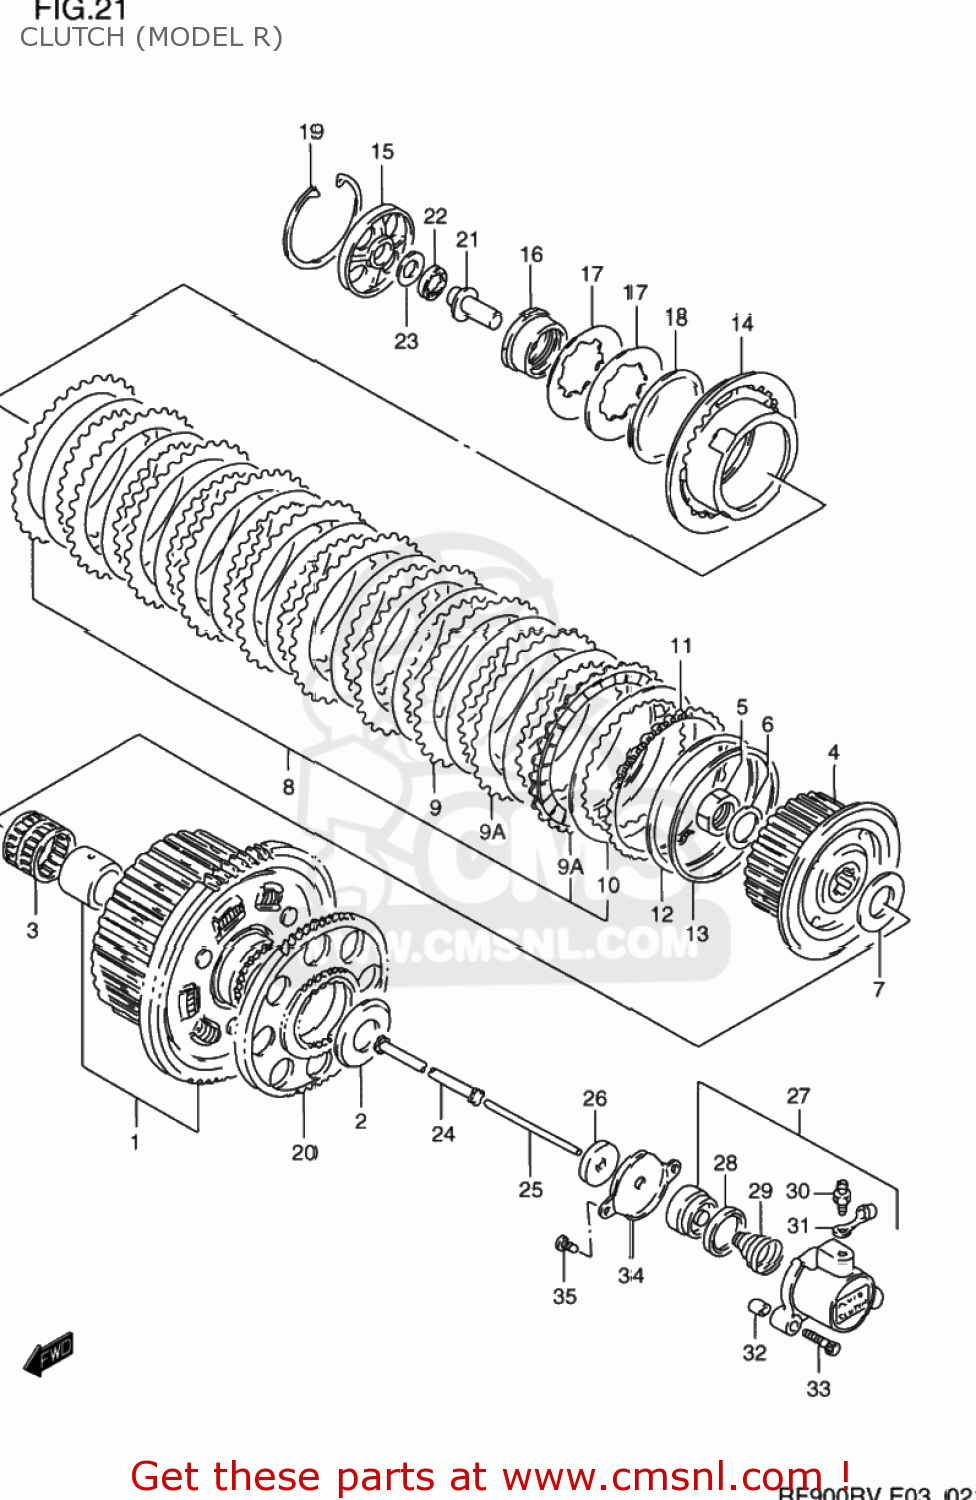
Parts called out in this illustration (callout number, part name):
1	GEAR ASSEMBLY,PRIMARY DRIVE
2	WASHER(25X54X2.5)
3	BEARING(35X40X35.8)
4	HUB,CLUTCH SLEEVE
5	NUT
6	WASHER
7	WASHER(25X50X2.5)
8	PLATE ASSY,CLUTCH
9	PLATE,CLUTCH DRIVE NO.1 (NAS)
9A	PLATE,CLUTCH DRIVE NO.2 (NAS)
10	PLATE,CLUTCH DRIVEN (NAS)
11	PLATE,CLUTCH DRIVE NO.2
12	WASHER
13	SEAT,CL SLEEVE HUB WAVE WASHER
14	DISC,CLUTCH PRESSURE
15	LIFTER,CLUTCH PRESSURE DISC
16	HOLDER,CLUTCH SPRING
17	WASHER
18	SEAT,CLUTCH SPRING
19	CIRCLIP
20	GEAR,GENERATOR DRIVE
21	PIECE,CLUTCH PUSH
22	BEARING(15X28X2)
23	WASHER(15.5X28X1)
24	ROD,CLUTCH
25	ROD,CLUTCH PUSH,L
26	SEAL,OIL(6X34X5.5)
27	CYLINDER,CLUTCH RELEASE
28	CUP
29	SPRING,CLUTCH CYLINDER
30	BLEEDER
31	CAP,BLEEDER
32	PIN
33	BOLT,CL.COVER
34	COVER,CLUTCH RELEASE CYLINDER
35	SCREW
